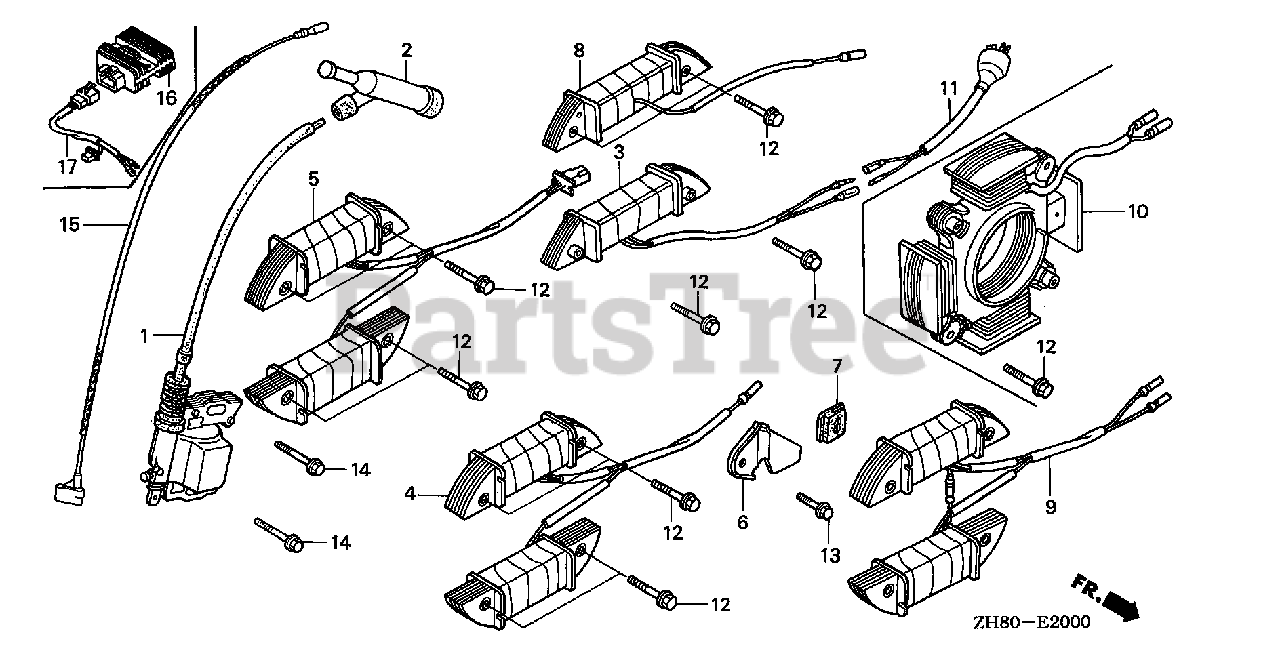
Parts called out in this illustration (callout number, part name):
1	COIL ASSY., IGNITION
2	CAP ASSY., NOISE SUPPRESSOR (NICHIWA Y-EZ RTFM256)
14	BOLT, FLANGE (6X25) (CT200)
15	WIRE, STOP SWITCH (370MM)
